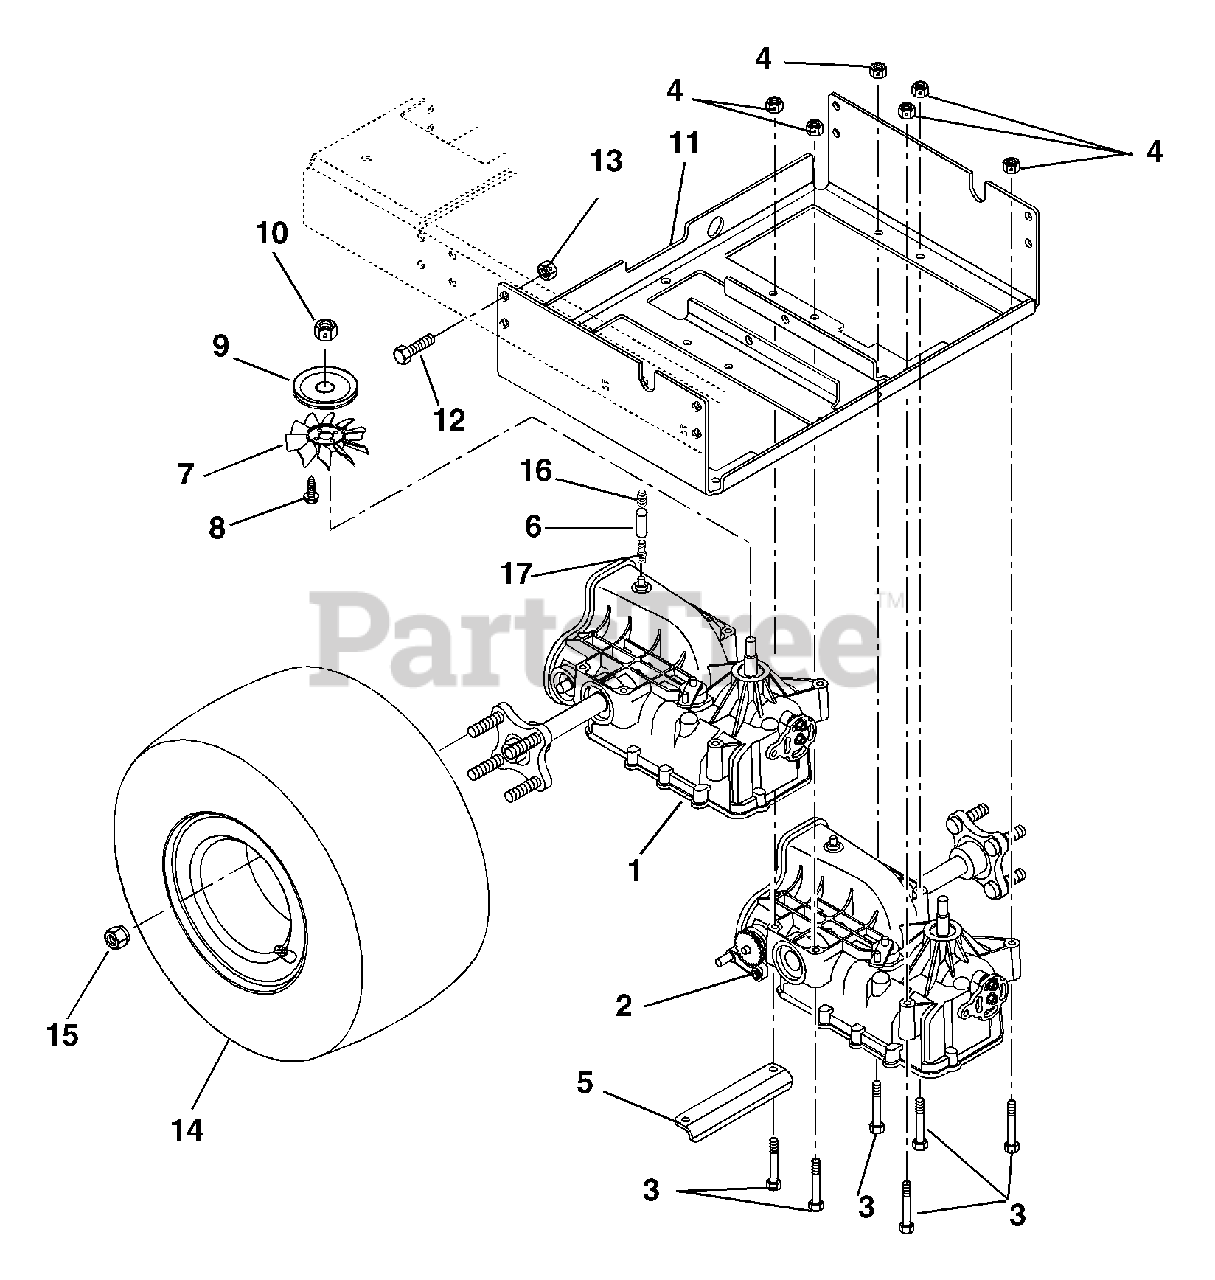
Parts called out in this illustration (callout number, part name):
1	Transaxle Hydro-Gear Right Hand
2	Transaxle Hydro-Gear Left Hand
3	Bolt-Hex .31-18 x 2.50 Grade 5
4	Nut-Locking-Center .31-18
5	Transaxle Bracket
6	Hose-Vent
7	Fan
8	Screw-Tapping 10-24 x .75 Hex Washer Head
9	Sheave-Transaxle
10	Nut-Locking-Top .50-20
11	Transmission Cradle
12	Bolt-Hex .38-16 x .75 Grade 5
13	Nut-Locking-Center .38-16
14	Tire/Wheel 18 x 8.50-8
14	Rim for 18 x 8.50-8 Tire
14	Tire 18 x 8.50-8
15	Nut-Lug .50-20
16	Cap-Vent 1/2" Hydro-Gear
17	Fitting-Straight 1/2" O-Ring Hydro-Gear
